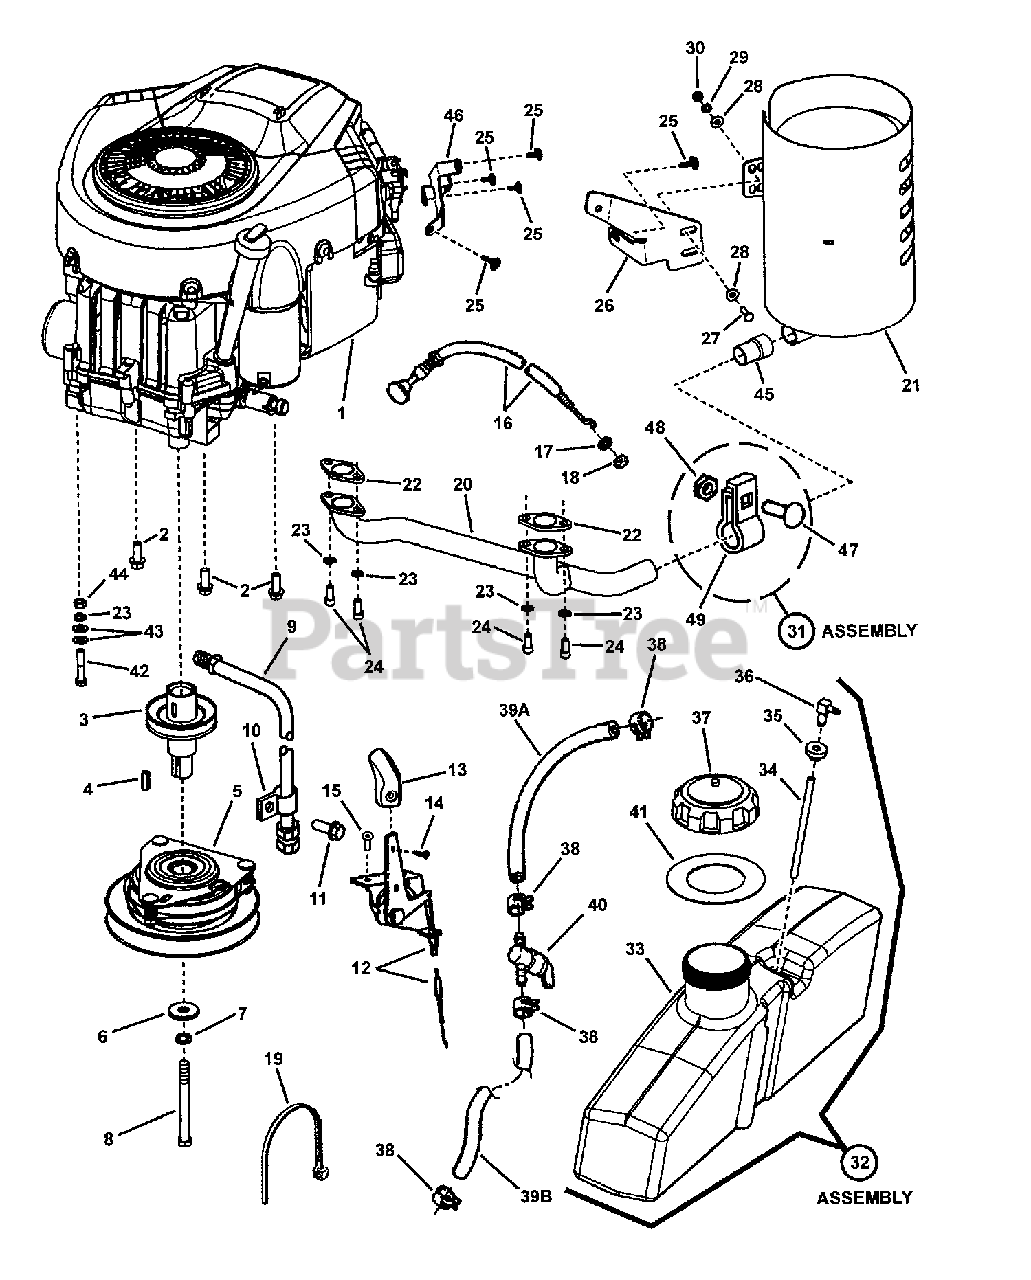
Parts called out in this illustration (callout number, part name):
1	* ENGINE, 20 HP Briggs Intek Twin
2	SCREW, 3/8-16 x 1" Hex Washer Self-Tap
3	ASSEMBLY, Engine Pulley
4	KEY, 1/4 Square x 1"
5	CLUTCH, Ogura JD-11
6	WASHER, .468 ID x 1.50 OD x .188 Flat
7	WASHER, 7/16" Split Lock
8	SCREW, 7/16-20 x 4-1/2" Hex Head Cap, GR 5
9	HOSE, Oil Drain
10	HARNESS CLIP, 5/8"
11	SCREW, 5/16-18 x 5/8" Hex Washer Self-Tap, GR 2
12	CABLE, 48" Throttle Control
13	KNOB, Throttle, Red RZT
14	SCREW, #10-16 x 3/4" Pan Head Self-Tap
15	SCREW, 1/4-20 x 5/8" Pan Head Self-Tap (Torx)
16	CABLE, 54" Choke Control
17	WASHER, 3/8" Internal Tooth Lock
18	NUT, 3/8-24 Hex, GR B
19	CABLE TIE, 7"
20	MANIFOLD, B&S V-Twin Intek
21	MUFFLER, RZT
22	GASKET, Exhaust, 20 HP Intek
23	WASHER, 5/16" Split Lock
24	SET SCREW, 5/16-18 x 3/4" Socket Head, GR 8
25	SCREW, 1/4-20 x 3/4" Hex Head Flange, GR 5, YZ
26	BRACKET, Muffler 20/22HP Briggs
27	SCREW, 1/4-20 x 3/4" Hex Head Cap, GR 5
28	WASHER, .28 x .63 x .06 Flat, GR 5
29	WASHER, 1/4" Split Lock
30	NUT, 1/4-20 Hex, GR 5 or B
31	ASSEMBLY, Clamp
32	ASSEMBLY, Fuel Tank, RZT
33	FUEL TANK
34	DIP TUBE
35	GROMMET
36	ELBOW, 90 Degree
37	CAP, Fuel, 3-1/2"
38	CLAMP, Fuel Line
39A	HOSE, Fuel, .25 I.D. x 5" long
39B	HOSE, Fuel, .25 I.D. x 14" long
40	VALVE, Fuel Shut-Off
41	SEAL, Tank
42	SCREW, 5/16-18 x 1-3/4" Hex Head Cap, GR 5, YZ
43	WASHER, .34 x .69 x .08 Flat
44	NUT, 5/16-18 Hex, GR 5 or B
45	TUBE, Manifold Extension
46	Bracket, Fuel Pump
47	BOLT, 5/16-18 x 1-1/4" Square Neck Carriage
48	NUT, 5/16-18 Hex Flange Lock, GR 5
49	CLAMP, Muffler
